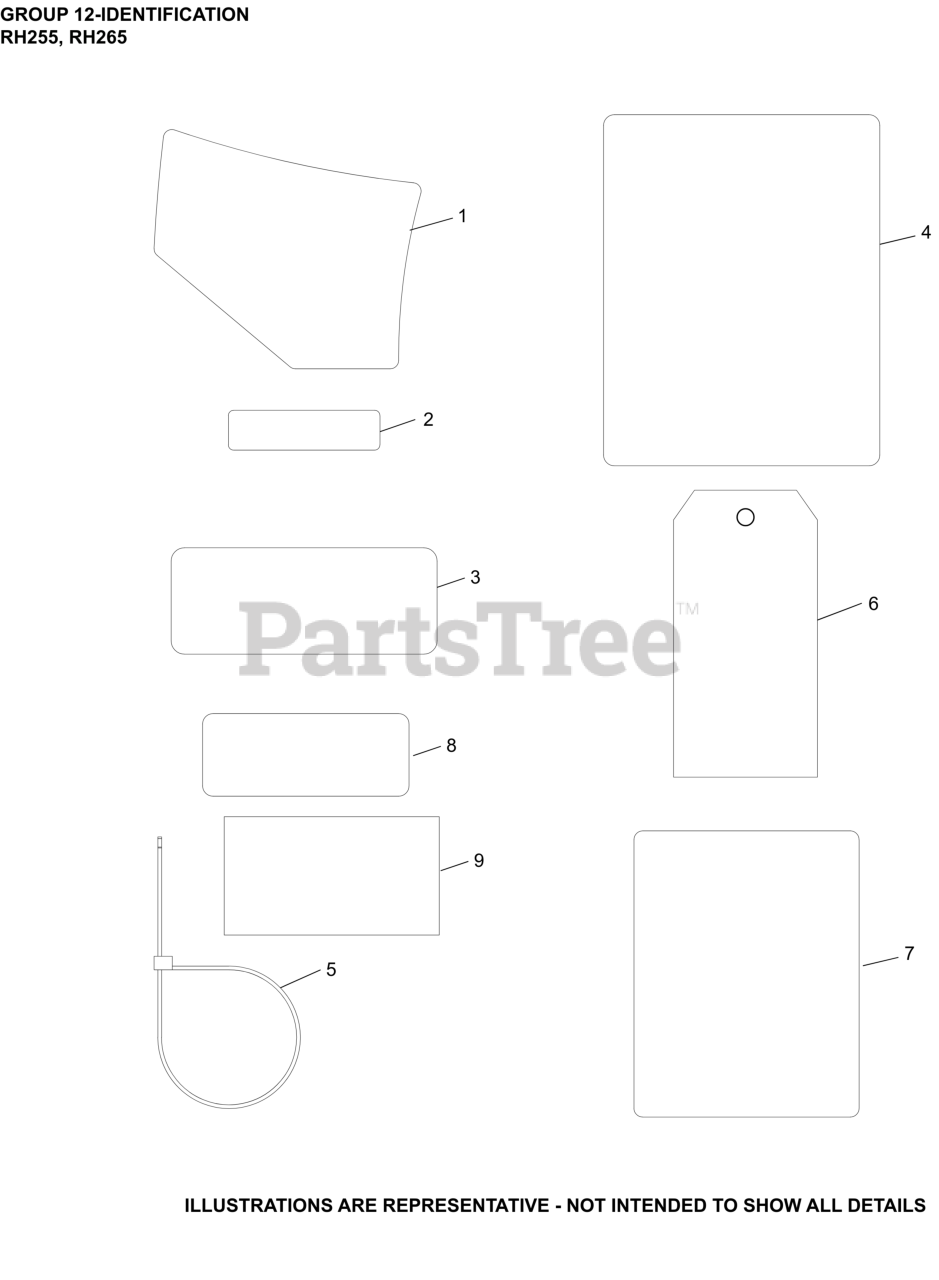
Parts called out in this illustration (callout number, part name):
4	DECAL, WARNING
7	LABEL, CLEAR LAMINATION
8	DECAL, ETHANOL WARNING
